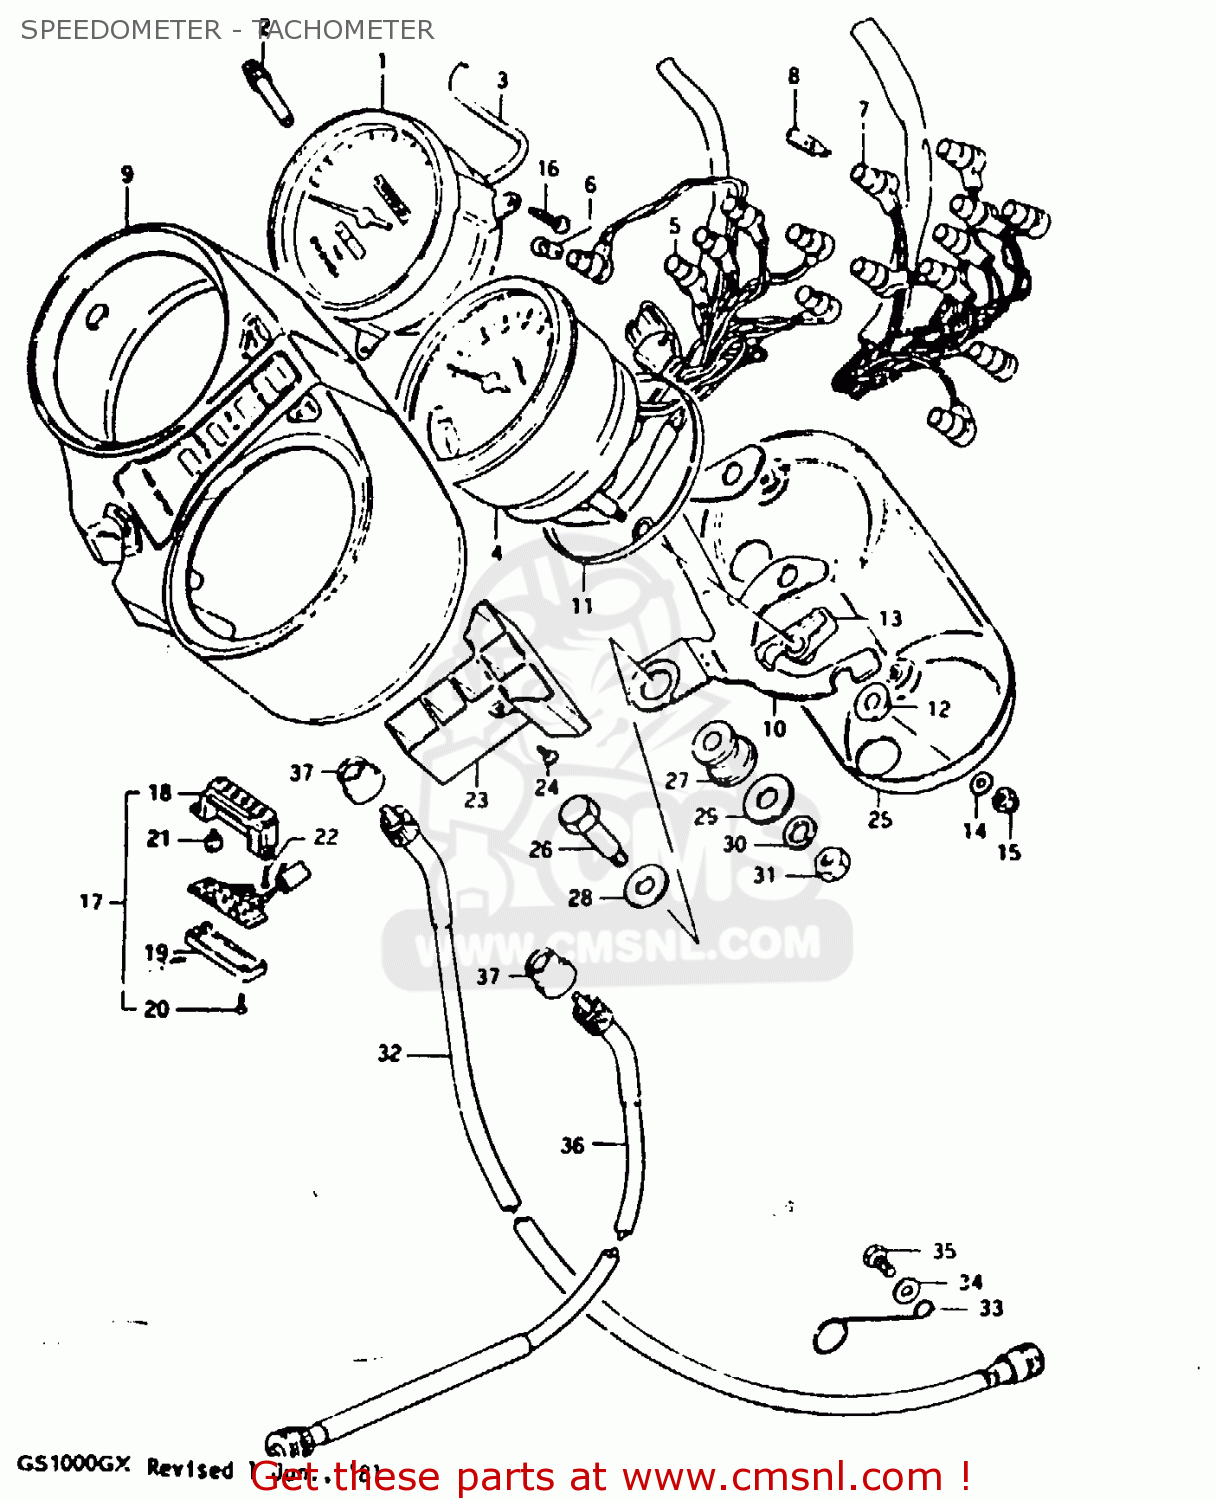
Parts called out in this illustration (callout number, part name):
1	METER,SPEEDOMETER
2	KNOB
3	WIRE,LEAD
4	TACHOMETER
5	SOCKET,METER
6	BULB(12V3.4W,STANLEY,A72A)
7	SOCKET,SPEEDOMETER
8	BULB(12V3.4W,T10)
9	CASE
10	BRACKET,COMBINATION METER
11	PLATE,METER,UNDER
12	CUSHION,METER (A)
13	CUSHION,METER (B)
14	WASHER
15	NUT
16	SCREW
17	INDICATOR ASSEMBLY,GEAR POSITION
18	CASE,GEAR INDICATOR
19	COVER,LWR
20	SCREW,GEAR INDICATOR
21	BULB(14V1.12W)
22	SCREW
23	CASE,PILOT BULB
24	SCREW
25	COVER,UNDER
26	BOLT
27	CUSHION,METER
28	WASHER
29	WASHER (8.5X29X1.6)
30	LOCK WASHER
31	NUT
32	CABLE ASSEMBLY,SPEEDOMETER
33	CLAMP,SPEEDOMETER CABLE
34	WASHER
35	BOLT, UPPER
36	CABLE ASSEMBLY,TACHOMETER
37	SEAL, CABLE END
